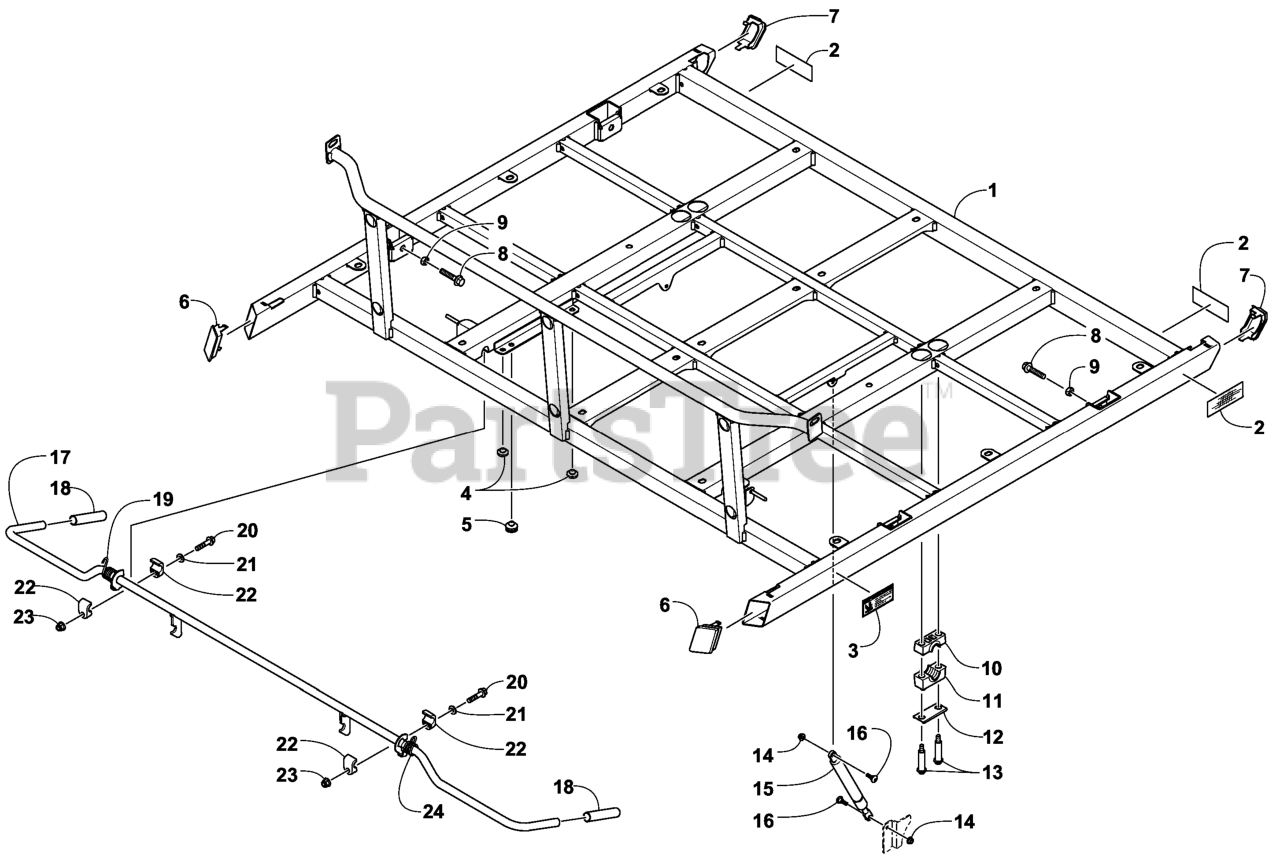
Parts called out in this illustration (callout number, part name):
1	FRAME-FLATBED
2	REFLECTOR-REAR
3	DECAL-WARNING, PINCH POIN
4	BUMPER-SEAT
5	BUMPER-CARGO BOX
6	CAP-FRONT, RH
6	CAP-FRONT, LH
7	CAP-REAR, RH
7	CAP-REAR, LH
8	SCREW-HFH
10	HOUSING-UPPER
11	HOUSING-LOWER
12	CAP-HOUSING
13	SCREW-SHOULDER
14	NUT-LOCK
15	SUPPORT-LIFT
16	SCREW-SHOULDER
17	LATCH-TILT
18	GRIP-LATCH ROD
19	SPRING-LATCH, RH
20	SCREW-HFH
22	BUSHING-PIVOT
23	NUT-HHF, LOCK, (NI)
24	SPRING-LATCH, LH
